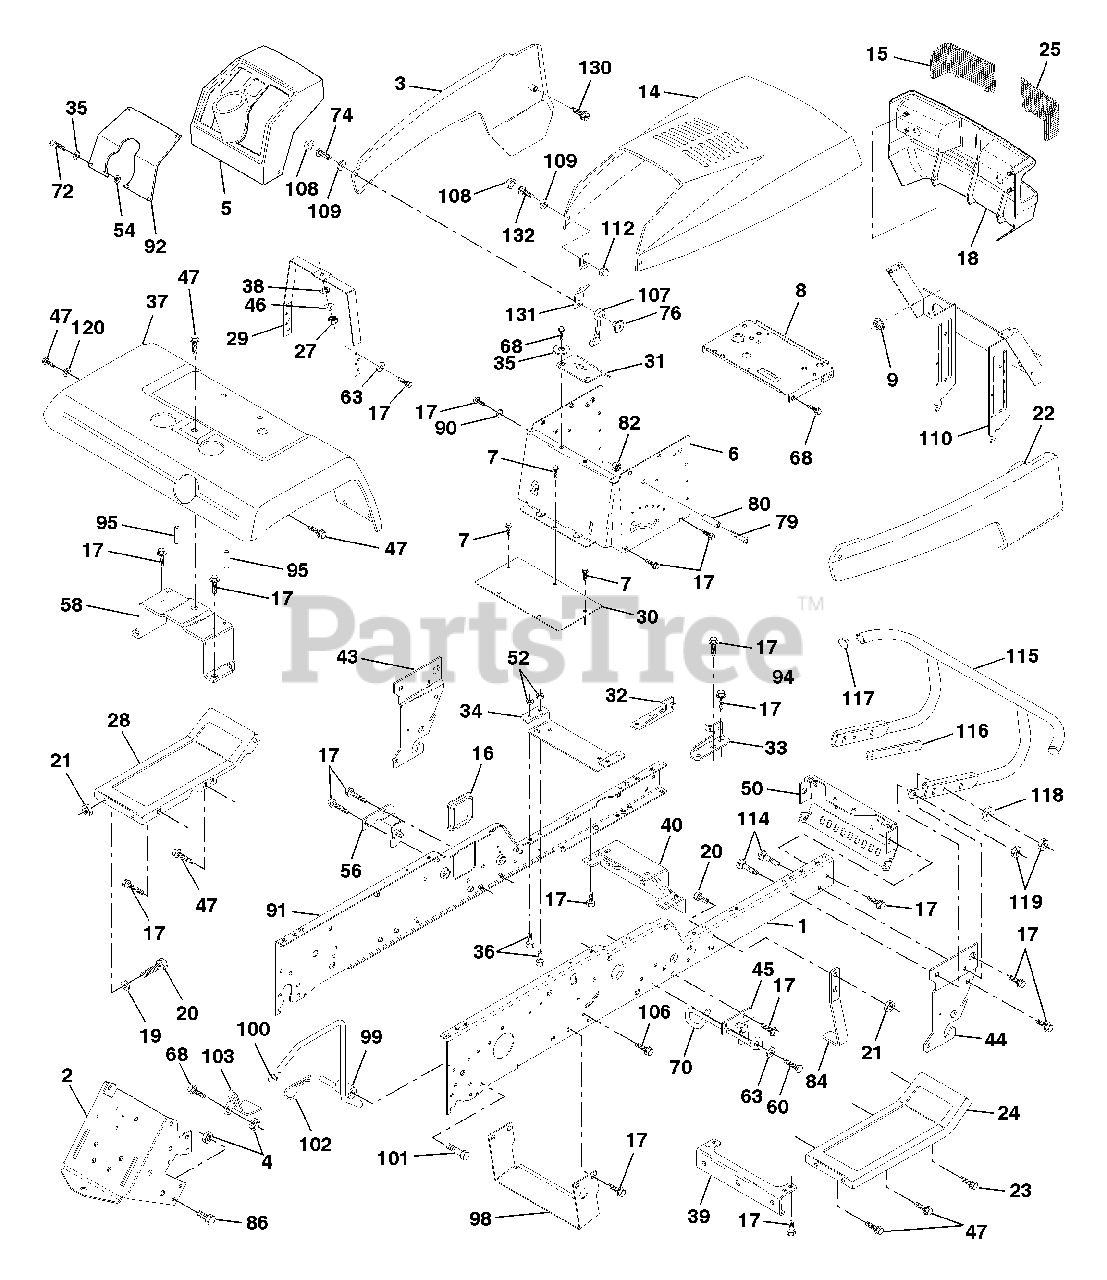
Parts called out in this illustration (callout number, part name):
1	Rail, Frame RH
2	Drawbar, Gt
3	Panel Asm., Side LH
4	Nut, Lock Hex 7/16 Unc
5	Dash, Plastic Black
6	Dash 1-PCS, Lower
7	Screw, Thd Cut 1/4-20 x 1/2
8	Support, Battery
14	Hood Asm., Pnt
15	Lens, Headlight LH
16	Cover, Access
17	Screw, Thdrol 3/8-16 x 3/4
19	Washer 13/32 x 13/16 x 12 Ga.
20	Bolt, Fin Hex 3/8-16 x 1
21	Nut, Crownlock 3/8-16 Unc
22	Panel Asm., Side RH
23	Screw Thdrol. 3/8-16 x 1 Ty-TT
24	Footrest, RH
25	Lens Headlight RH
27	Nut Fin Hex 1/4-20
28	Footrest, LH
29	Bracket, Support Dash
31	Brace, Support Steering
32	Bracket Asm., Frame Pivot Lh
33	Bracket Asm., Frame Pivot Rh
34	Bracket, Engine Support Rear
35	Washer 11/32 x 11/16 x 16 Ga.
36	Bolt, Fin Hex 5/16-18 x 3/4
37	Fender, Pnt.
38	Washer, Lock 1/4
39	Bracket, Axle Front
40	Bracket, Support Axle/Engine
43	Bracket, Spnsn Front Lh
44	Bracket, Spnsn Front Rh
45	Bracket Asm., Susp Chassis Rh
46	Washer 9/32 x 3/4 x 16 Ga.
47	Screw Thdrol 3/8-16 x 1/2
50	Bracket, Chassis Front
52	Locknut, Hex W/Ins 5/16-18 Unc
54	Nut 5/16-18
56	Bracket Asm., Susp Chassis Lh
58	Bracket Asm., Fender
60	Screw Thdrol 3/8-16 x 1-1/4
63	Washer 13/32 x 1 x 14 Ga.
68	Screw, Thdrol 5/16-18 x 1/2
70	Guide, Belt Mid Span
72	Screw, Mach Trhd 5/16-18 x 3/4
74	Screw, Machine #10-24
76	Nut, Weld #10-24
79	Screw, Machine #10-24 x 1/4
80	Spacer, Split
82	Nut #10-24
84	Stop, Over Center 44" 20/23" T. 94
86	Bolt, Fin Hex 7/16-14 Unc x 1
90	Washer, Lock External Tooth 3/8
91	Rail, Frame Lh
92	Plate, Silkscreen Dash
94	Clip, Fuel Line
95	Push Nut, Nylon
98	Bracket Chassis Skid
99	Rod Asm. Bypass
100	Cap Brake Parking Red
101	Screw Thdrol. 3/8-16 x 1-3/4
102	Retainer Spring 1"
103	Bracket Lock Bypass
106	Screw Thdrol. Hex Hd Zinc Mur
107	Latch, Chute Blk
108	Cap, Snap Black
109	Cap, Washer Snap
110	Pivot Asm. Grille/Hood Husq. VGT
112	Nut, Acorn, Hex #10-24
114	Bolt, Carriage 3/8-16 x 1-1/4
115	Bumper Asm.
116	Bracket Extension Bumper
117	Plug Plastic
118	Washer 13/32 x 13/16 x 16 Ga.
119	Nut Crownlock 3/8-16 UNC
120	Washer 13/32 x 1 x 16 Ga.
130	Screw, SLTD Hex Hd. W/Pl Washer
131	Bracket Support Hood/Panel YP
132	Screw Truss Hd. #10-24 x 3/8
